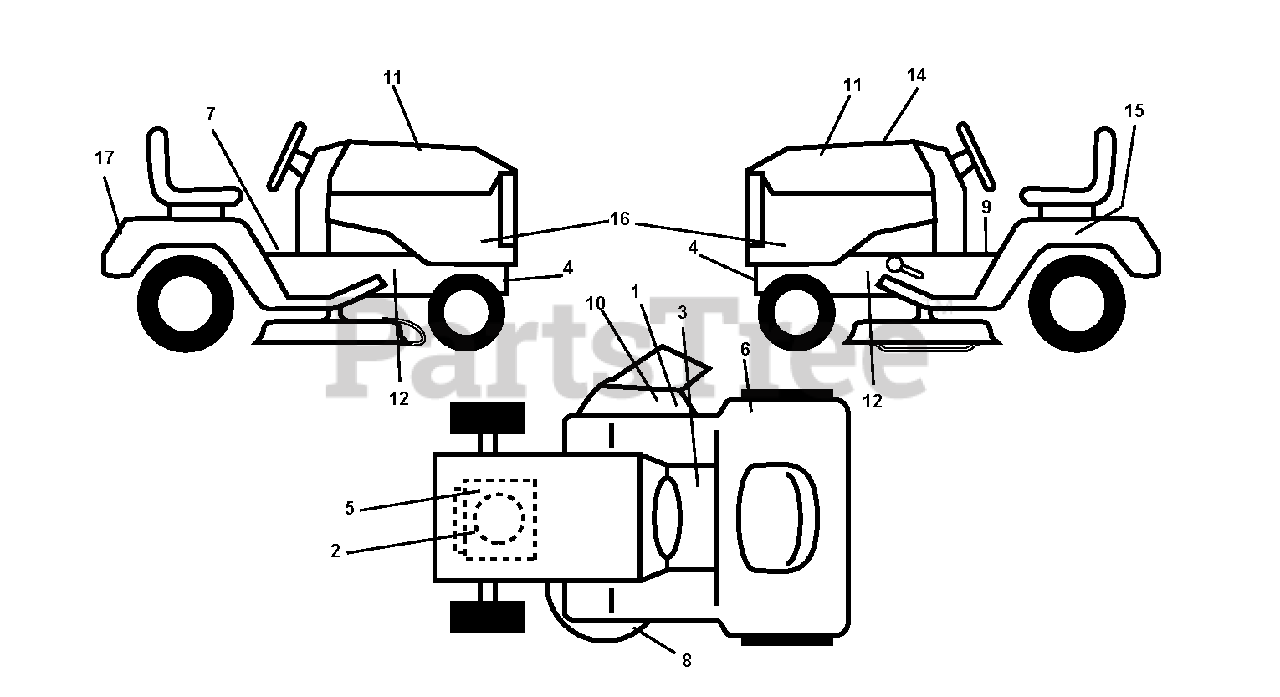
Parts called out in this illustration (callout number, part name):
1	DECAL, DEFLECT WARNING
8	DECAL.V-BELT.SCHEMATIC.36/38/9
9	DECAL PARK BRAKE
10	DECAL.INTERNATIONL.CUTFINGER
15	DECAL BTRY SYMBOLS
